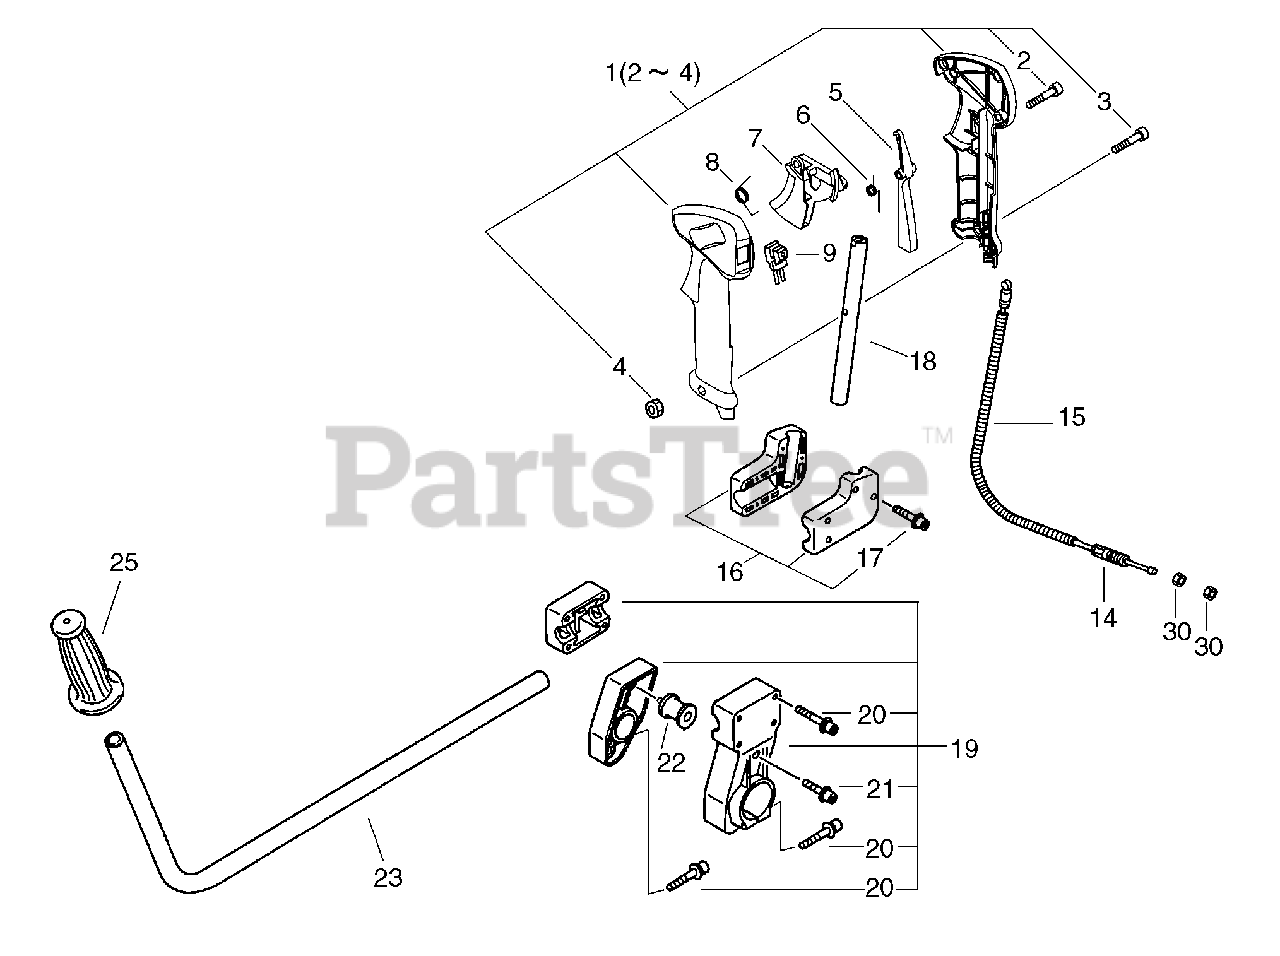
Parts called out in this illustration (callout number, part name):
1	CONTROL HANDLE ASSY
2	SCREW 4×16
3	SCREW 5×30
4	NUT M5
5	LOCKOUT, THROTTLE
6	SPRING, TORSION
7	TRIGGER, THROTTLE
8	SPRING, TORSION
9	SWITCH, ON-OFF
14	CABLE, THROTTLE
15	TUBE, FLEXIBLE 7×820
16	BRACKET, HANDLE
17	BOLT 5×25
18	HANDLE, REAR
19	BRACKET, HANDLE
20	BOLT M5×35
21	BOLT 5×14
23	HANDLE, FRONT
25	GRIP, HANDLE
